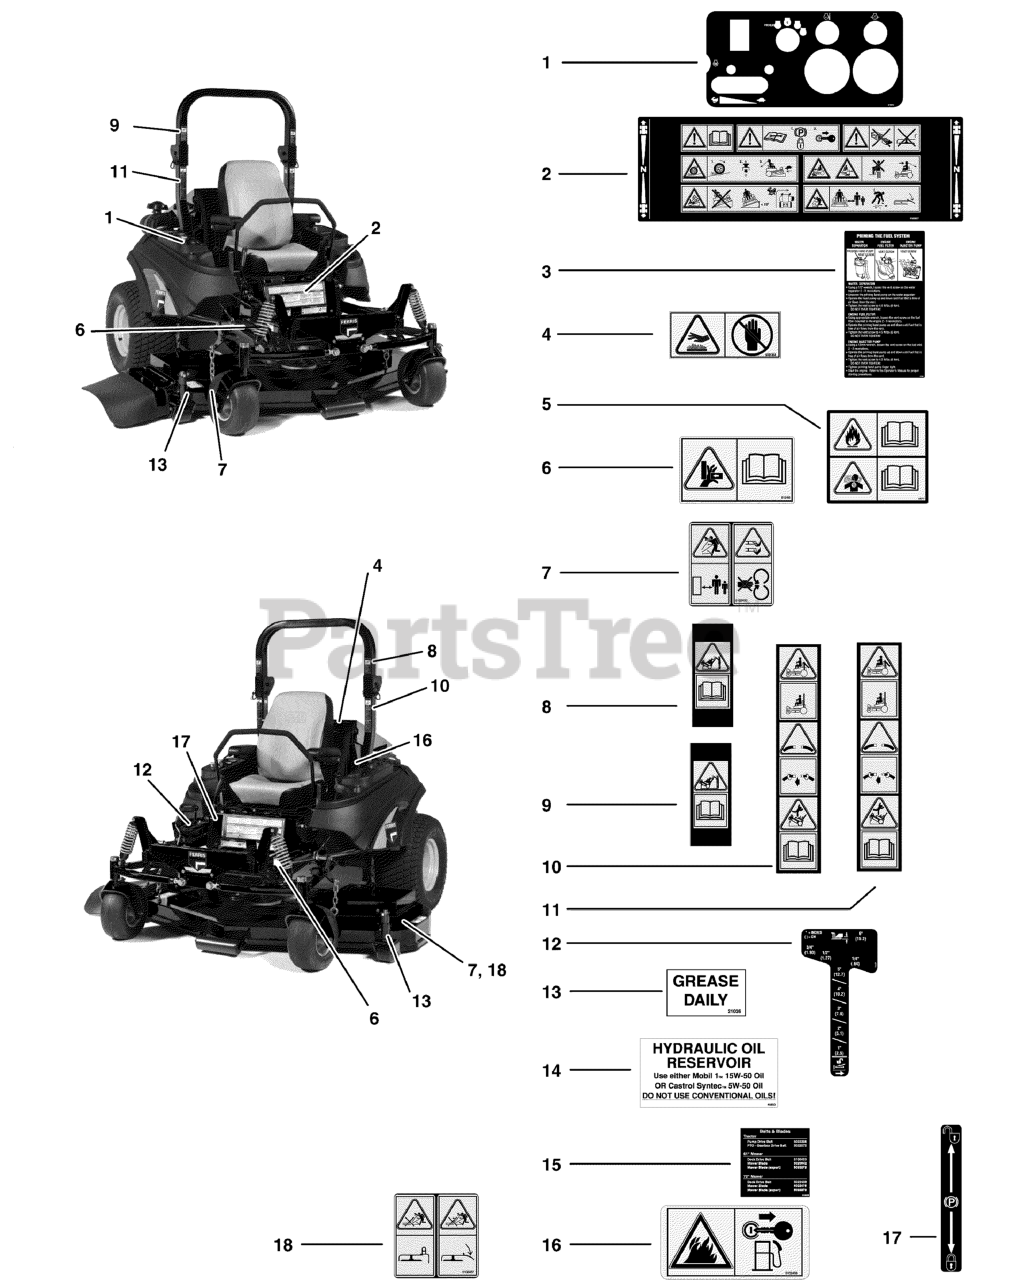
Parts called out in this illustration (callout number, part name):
1	DECAL, CONTROL PANEL, IS5000Z
2	DECAL, MAIN SAFETY, ANSI CE
3	DECAL, PRIMING INSTRUCTIONS
4	DECAL, HAND IN FLAME
5	DECAL, DANGER, CE
6	DECAL, PINCH POINT, CE
7	DECAL, DANGER, MOWER DECK, ANSI EXP
8	DECAL, SAFETY, CE ROPS, OBS
9	DECAL, SAFETY, CE ROPS, OBS
10	DECAL, SAFETY, CE ROPS
11	DECAL, SAFETY, CE ROPS
12	DECAL, HEIGHT OF CUT, IS5000Z
13	DECAL, GREASE DAILY
14	DECAL, OIL RESERVOIR
15	DECAL, BELT & BLADE, IS5000Z
16	DECAL, FIRE ANSI EXPORT
17	DECAL, PARKING BRAKE SYMBOLS
18	DECAL, DANGER DISCHARGE ANSI EXP
